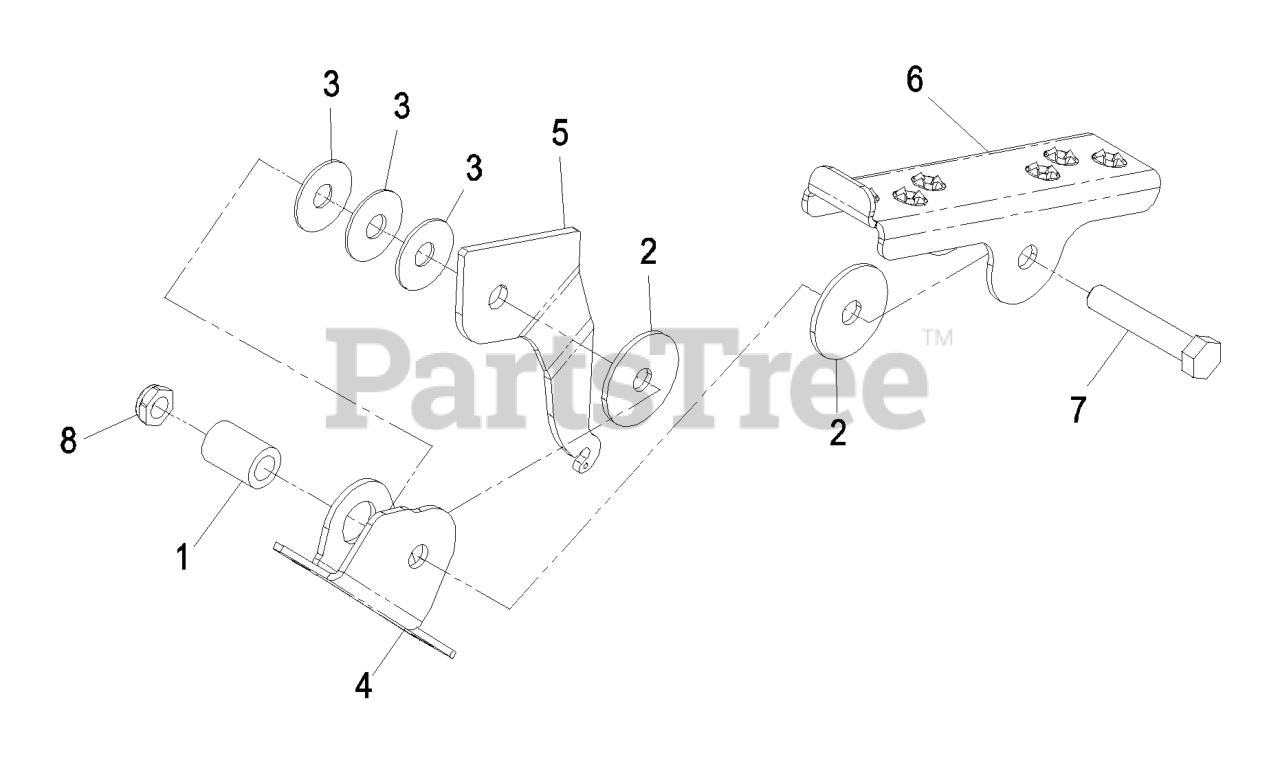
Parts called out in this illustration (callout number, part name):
1	Spacer- Roller
2	Disc, Friction
3	Washer, Spring Disc
4	Bracket, Pedal Pivot
5	Bracket, Pedal Link
6	Channel, Pedal Link
7	Screw, Hh 1/2-13 X 2 3/4
8	Nut, Nyloc 1/2-13 Thin
